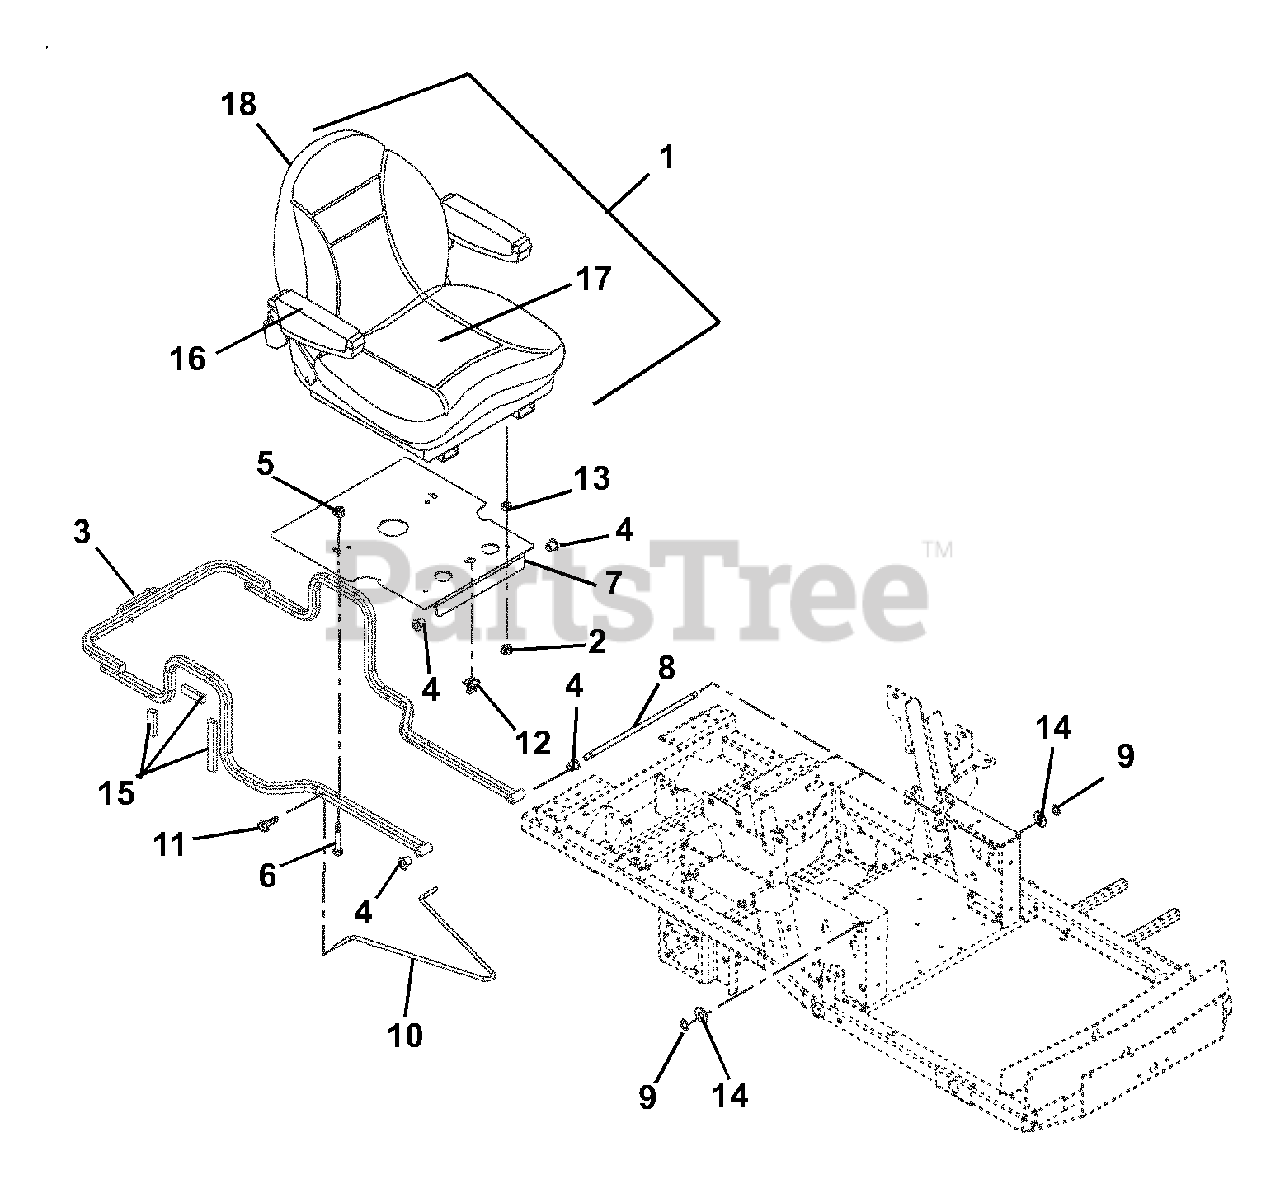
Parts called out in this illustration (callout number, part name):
1	Seat, Suspension
2	Nut, Locking Top Flange .31-18
3	Weldment, Hood Frame
4	Bushing, Flange .515 x .750 x .745 x 1.00
5	Nut, Locking Top Flange .38-16
6	Bolt, Rib Neck .38-16 x 1.50
7	Weldment, Seat Pivot Mount
8	Rod, Seat Frame Pivot
9	Ring, Retaining External .500 x .050
10	Rod, Prop
11	Screw, Tapping .25-20 x .50 Hex Washer Head
13	Bushing, Sleeve .377 x .624 x .235
14	Washer, Flat Steel .531 x 1.06 x .095
15	Tape, VHB
16	Kit, Arm Pad
17	Kit, Seat Cushion
18	Kit, Back Cushion
